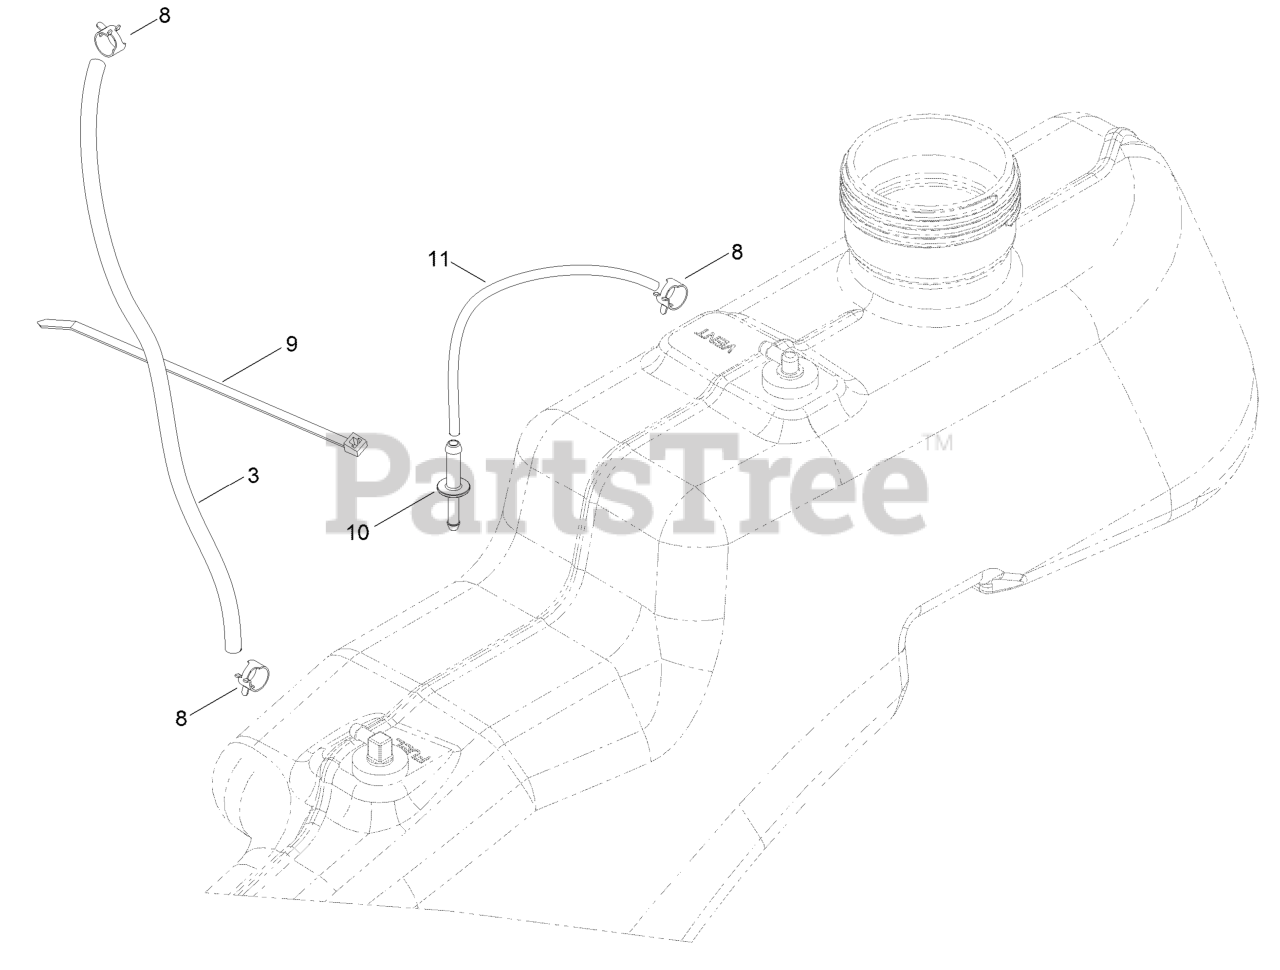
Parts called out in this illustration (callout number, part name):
3	HOSE-FUEL
8	CLAMP-HOSE
9	TIE-CABLE
10	ADAPTOR-ORIFICE
11	HOSE-FUEL
